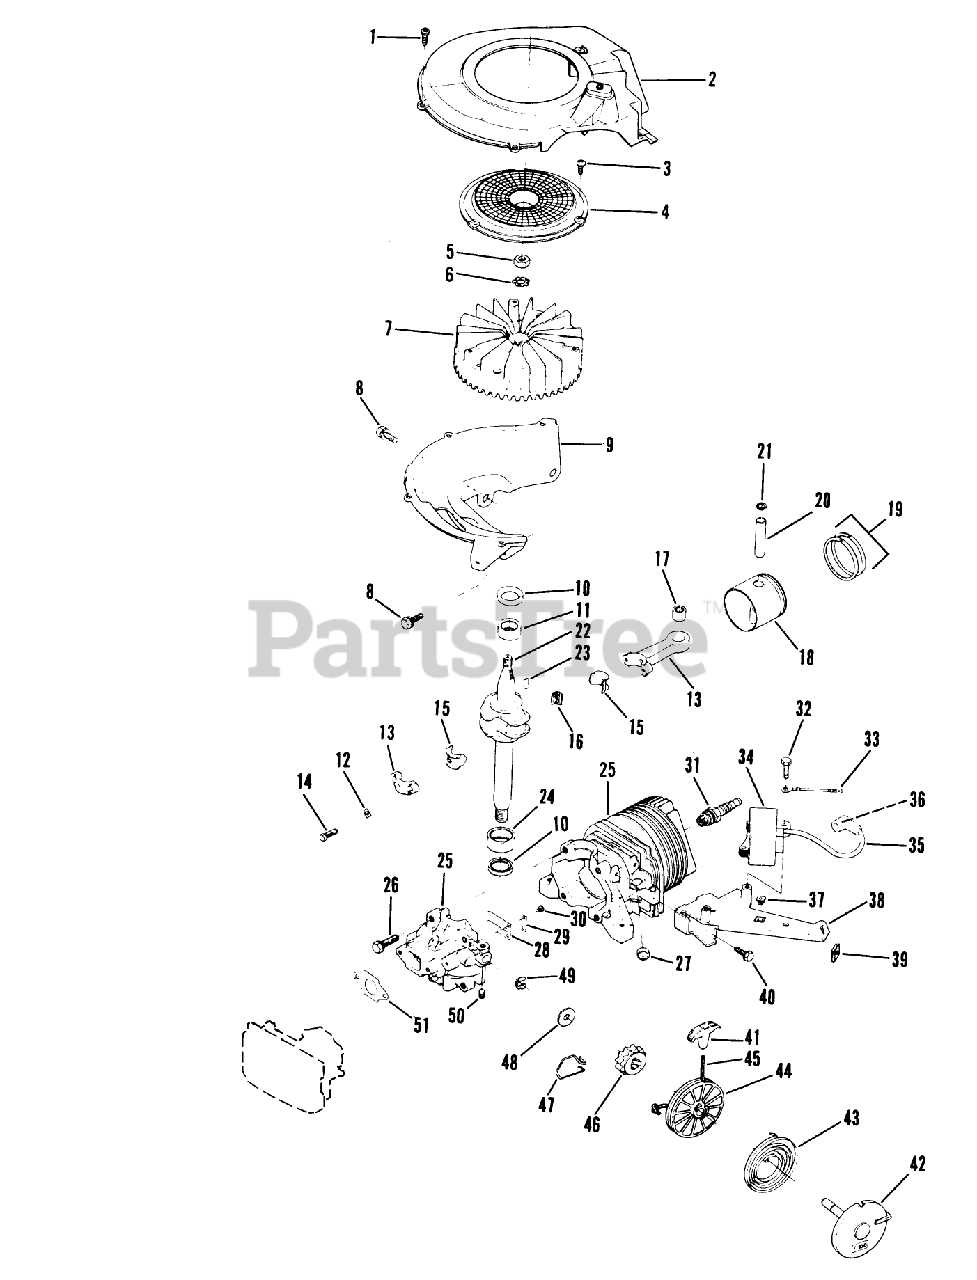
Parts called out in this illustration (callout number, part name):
1	SCREW S
2	AIR BAF&EYELET S
3	SCREW F
5	NUT
8	SCREW-SEMS
9	SHROUD BASE S
11	BEARING V
14	SCREW
15	LINER ASM
17	BEARING AY F
21	RING-RETAINING
23	KEY
24	BEARING V
26	SCREW S
27	PLUG-CORE VF
29	PLATE-BACKUP, REED
35	HT LEAD&COVER XEV
37	NUT-CLIP
39	NUT - SPEED S
41	HANDLE STARTER S
43	SPRING S
47	SPRING F
48	WASHER S
50	SET SCREW
51	GASKET CARB S
